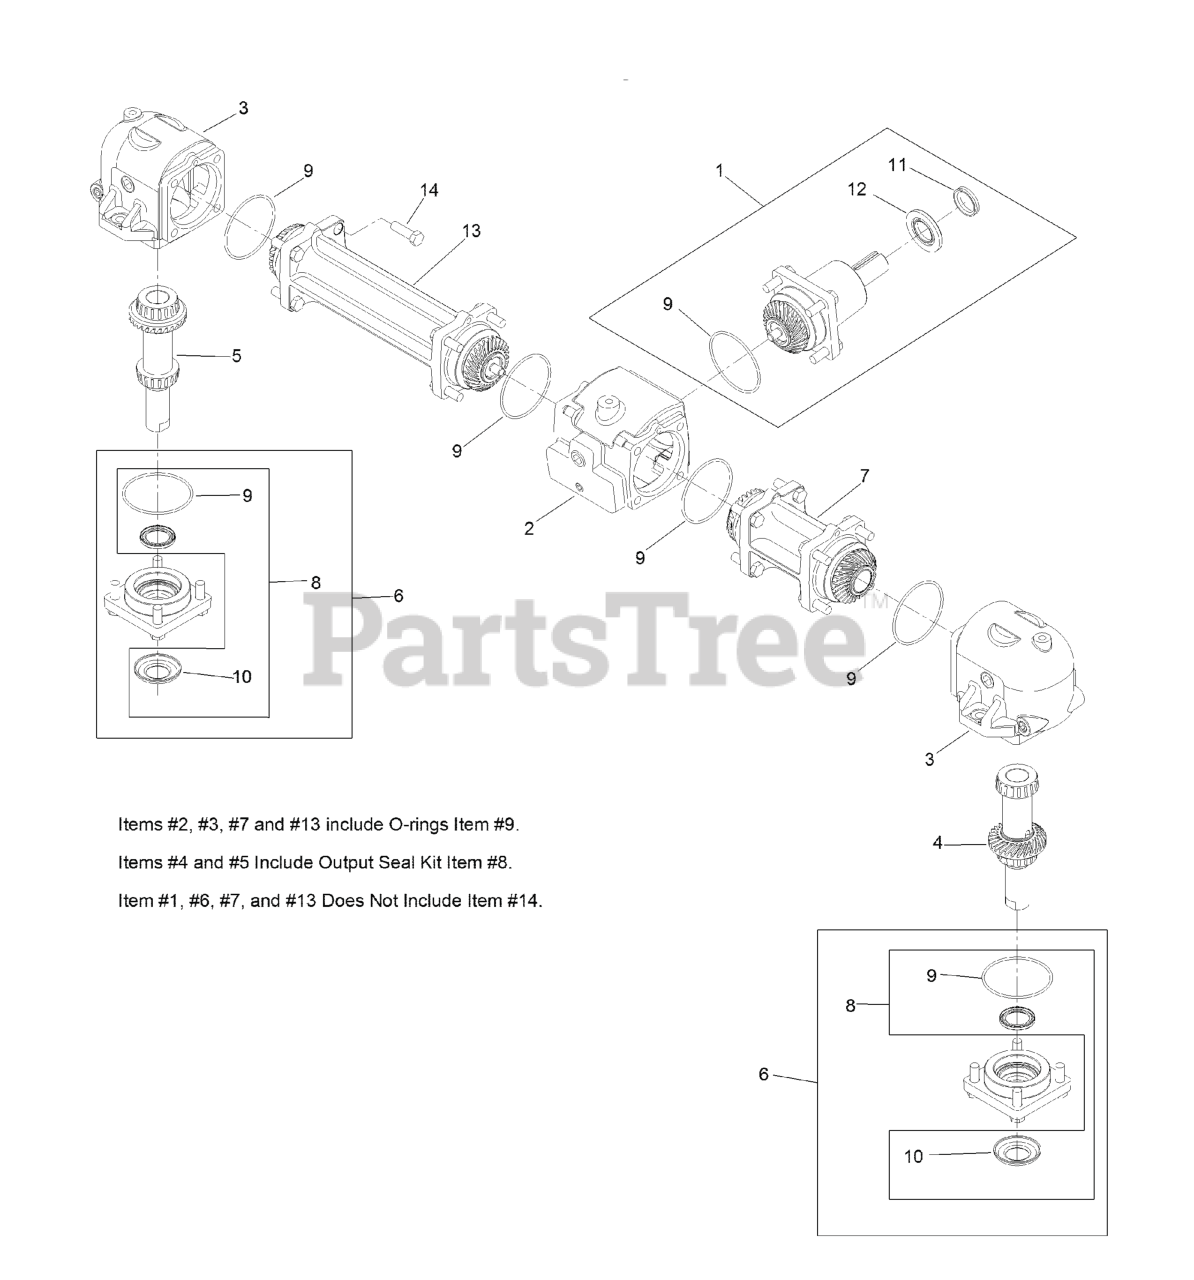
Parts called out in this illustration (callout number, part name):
1	PINION-INPUT
2	HOUSING-CENTER
3	HOUSING-END
4	OUTPUT SHAFT AND GEAR-LH
5	OUTPUT SHAFT AND GEAR-RH
6	CAP-OUTPUT
7	TUBE-CONNECTOR, SHORT
8	OUTPUT SEAL KIT
9	SEAL-O-RING
10	WASHER-CUPPED
11	SEAL-V-RING
12	SEAL-INPUT
13	CONNECTOR-TUBE, LONG
